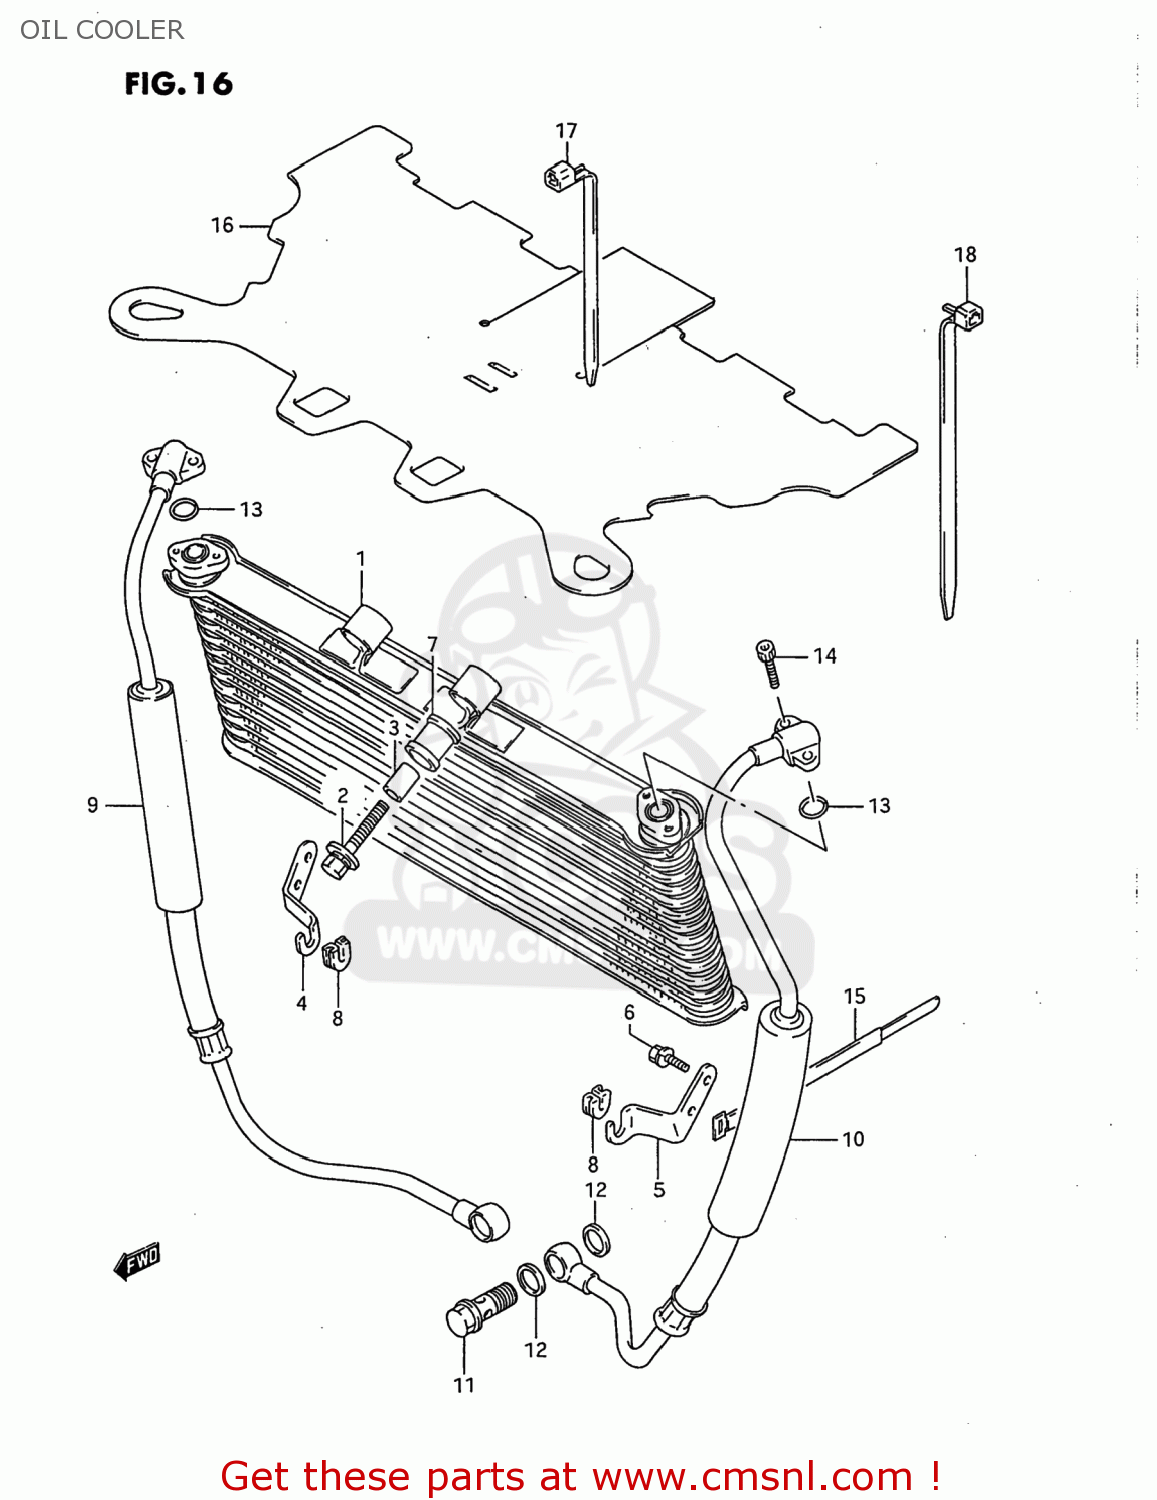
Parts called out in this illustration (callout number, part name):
1	COOLER ASSY,OIL
2	BOLT(8X40)
3	SPACER(8.5X12X25)
4	BRACKET,OIL COOLER,RIGHT
5	BRACKET,OIL COOLER,LEFT
6	BOLT
7	CUSHION,OIL COOLER NO.1
8	CUSHION,OIL COOLER NO.2
9	HOSE,OIL COOLER,R
10	HOSE,OIL COOLER,R
11	BOLT UNION
12	GASKET(16X22X2) (NAS)
13	O RING(D:2.4,ID:12.3)
14	BOLT,OIL FILLE
15	CLAMP(L:235)
16	PLATE,AIR GUIDE
17	CLAMP L:165
18	CLAMP(L:235)
